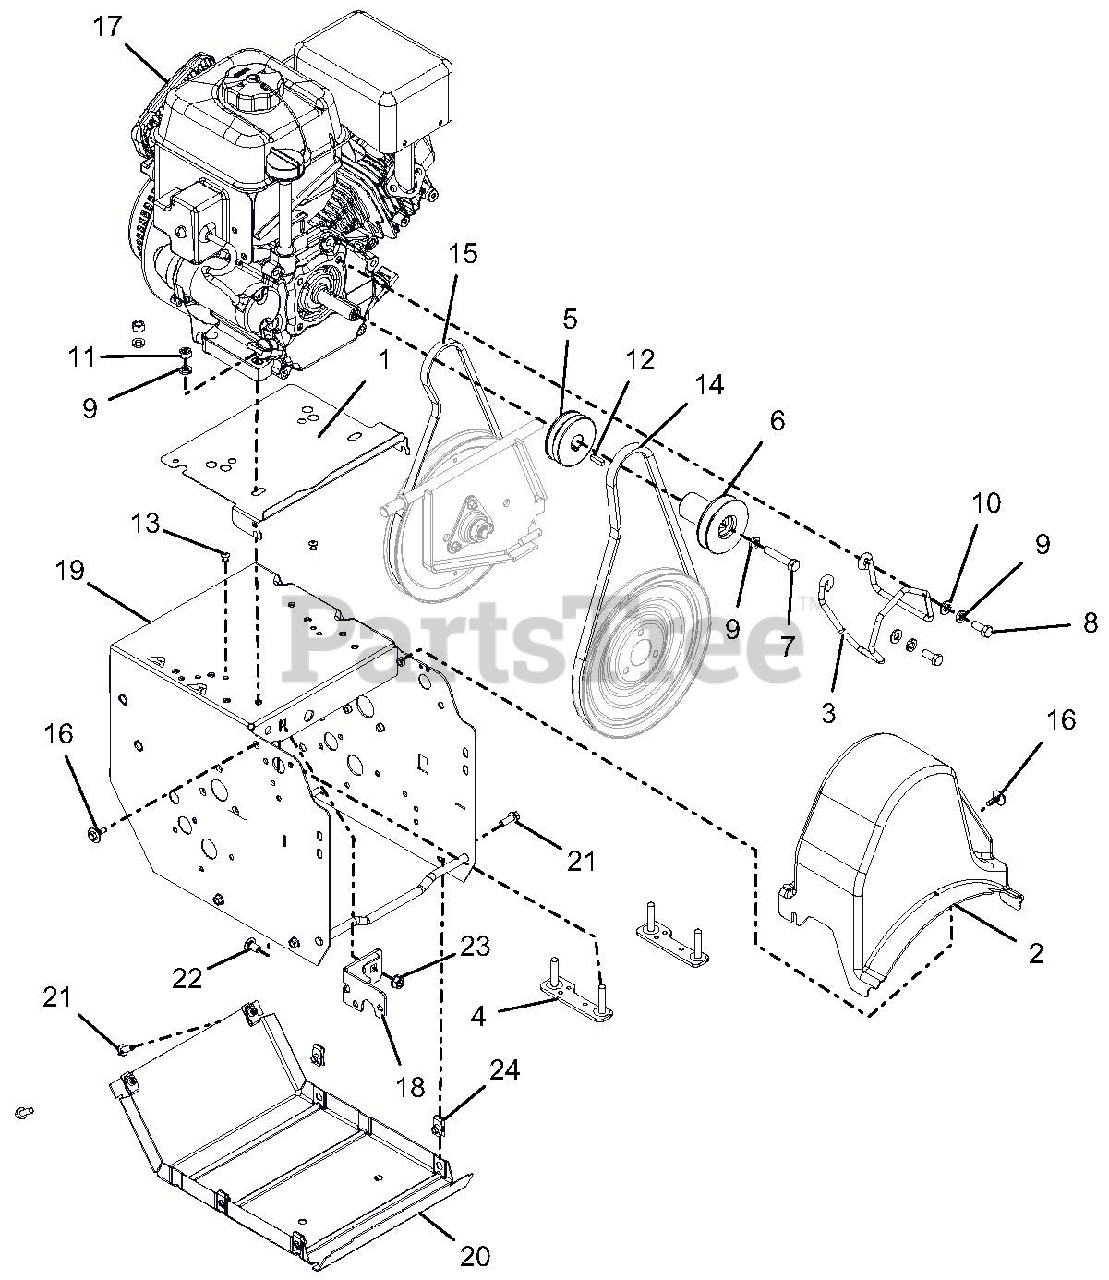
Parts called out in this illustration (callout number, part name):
1	BAFFLE,ENGINE,SMALL BLOCK
2	COVER, COMPACT BELT
3	FINGER, BELT
4	STRAP, ENGINE BOLT-WELDMENT
5	SHEAVE, TRACTION-COMPACT TRACK
6	SHEAVE,AUGER 3/4" PM
7	@BLT-HEX .31-24X1.75 GR5 YWZC
8	BLT-HEX .31-24X.75 YWZC GR5
9	WSHR-LK .312X.097 HVY YWZC
10	@WSHR-FL-STL.344X.688X.065YWZC
11	@NUT-HEX .31-18 YWZC
12	KEY-SQ .188X.75X.188
13	RVT-POP .187 YZ
14	V-BELT, HA-RAW EDGE
15	V-BELT, 3L-WRAPPED
16	SCR-TAP .25-20X.5 CAPTIVE
17	ENGINE, AX208 GEN 2 120V/60W
17	ENGINE, ARIENS 208CC 120V, 60W
17	ENGINE, ARIENS AX208 120V/60W
18	WELDMENT, FRAME BRACKET
19	FRAME, 920/921
20	COVER, BOTTOM
21	BLT-HEX .25-20X.75 HWH YZ GR5
22	@BLT-RHDSSQNK .31-18X.62 G5YZ
23	@NUT-LK-TOP-FLG .31-18 YWZC
24	NUT-RTNR .25-20X.56
